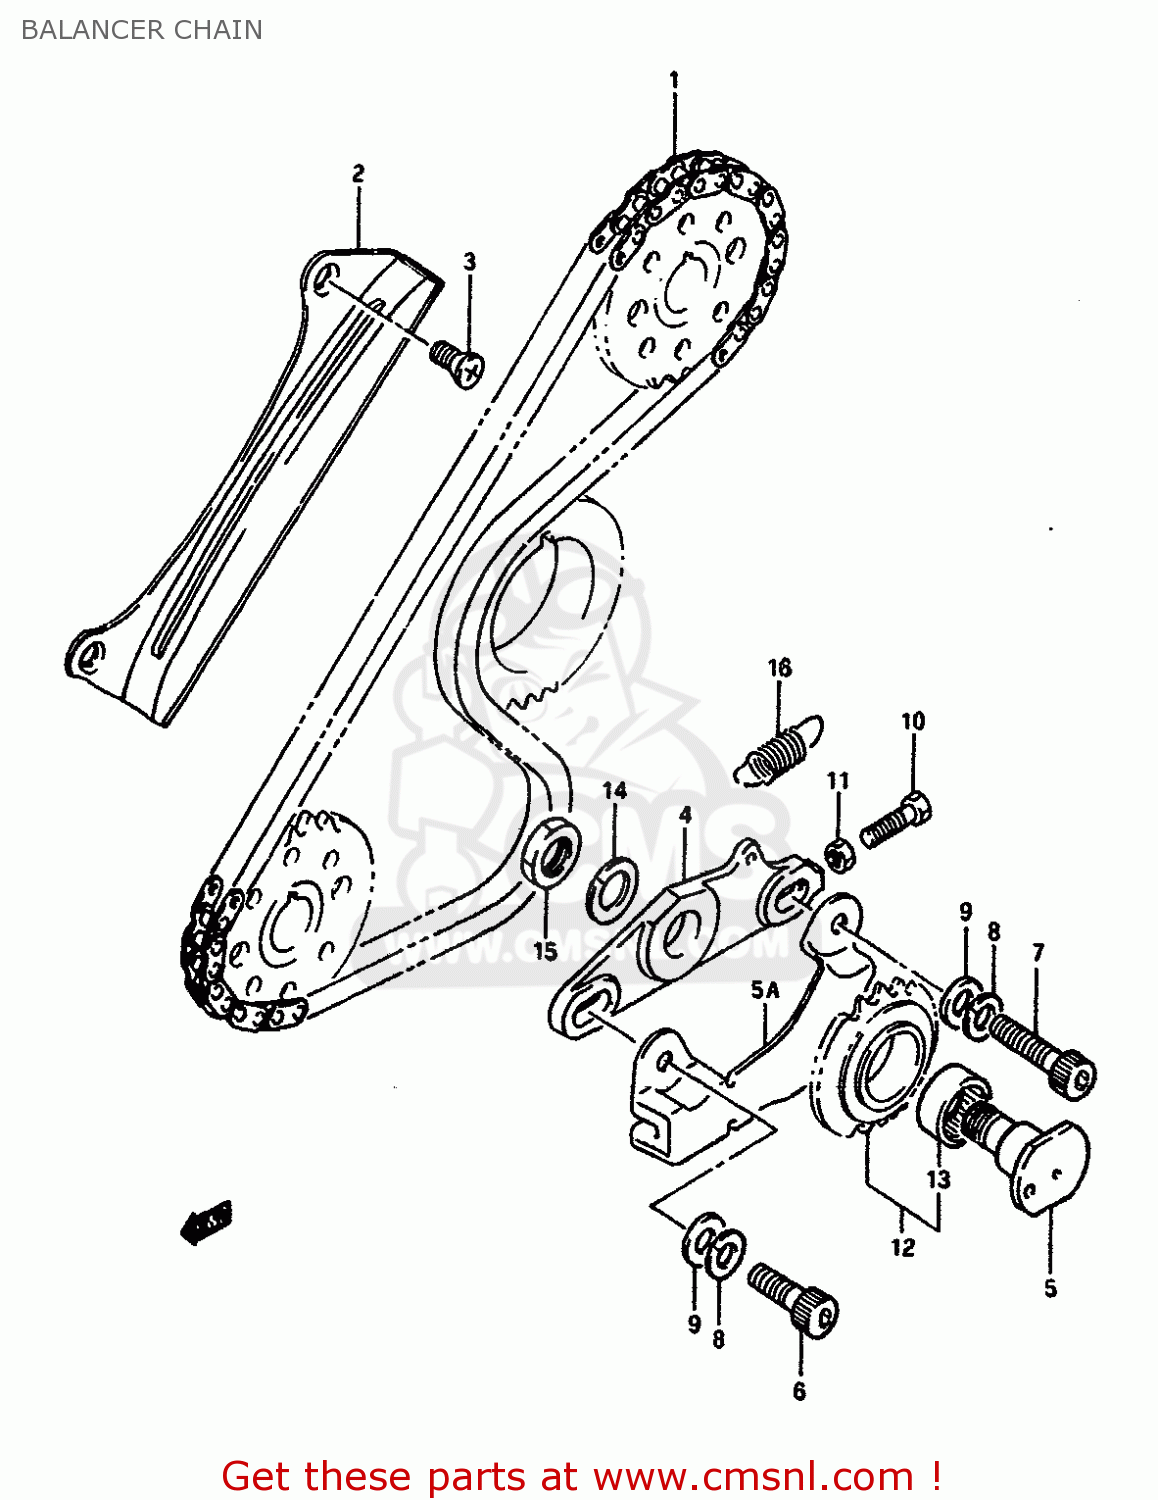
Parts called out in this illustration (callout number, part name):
1	CHAIN,BALANCER
2	GUIDE,BALANCER CHAIN
3	SCREW
4	BRACKET,BALANCER CHAIN
5	SHAFT,BALANCER CHAIN TENSIONER
5A	GUIDE,BALANCER CHAIN TNSN
6	BOLT(8X22)
7	BOLT, REAR (8X30)
8	LOCK WASHER
9	WASHER
10	BOLT 5X20
11	NUT
12	SPRKT,BALANCER CHAIN TENSIONER
13	BEARING(17X23X12)
14	WASHER,LOCK 12
15	NUT
16	SPRING
